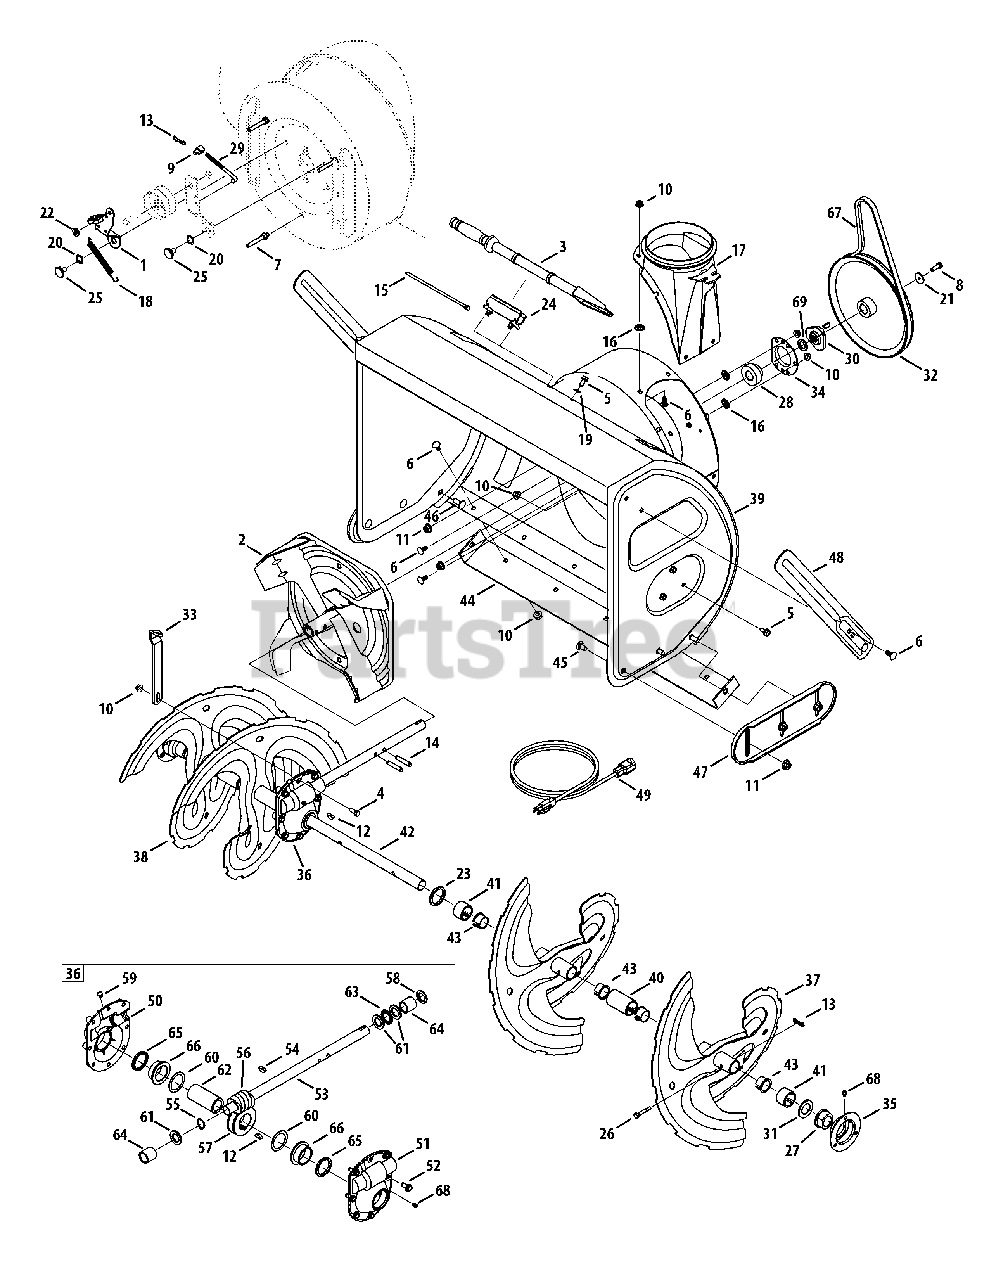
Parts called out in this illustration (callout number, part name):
1	Bracket Assy, Auger Brake
2	Impeller, 16"
3	Tool, Cleanout
4	Scr,Hex Cap, 5/16-18 x 1.00
5	Screw, 5/16-18 x .750
6	Screw, Carriage, 5/16-18 x .75
7	Screw, 5/16-18 x .4300
8	Screw, 5/16-24 x .875
9	Ferrule
10	Nut, Flnge Lk, 5/16-18
11	Nut, Flg Lk, 3/8-16
12	Key, Woodruff,1/4 x 3/4
13	Pin, Bowtie Cotter
14	Pin, Spirol, 5/16 x 1.75
15	Tie, Cable
16	Nut, Push
17	Adapter, Chute, 6"
18	Spring, Extension
19	Washer, .349 x .879 x .063
20	Washer, .625 x .885 x .015
21	Washer, Flat, .34 x 1.50 x .150
22	Washer, .344 x .75 x .12
23	Washer, 1.01 x 1.86 x .06
24	Clip, Mounting
25	Screw, Shoulder, .625 x .17
26	Pin, Shear, .25 x 1.75
27	Bearing, Flange w/Flats
28	Bearing, Self Aligning
29	Rod, Auger Idler
30	Pulley, Adapter, .75 Dia.
31	Spacer, 1.004 x 1.375 x .25
32	Pulley, Auger Drive, 10.0
33	Bracket, Gear Box Support
34	Housing, Bearing
35	Housing, Bearing
36	Gear Box Assembly, Auger
37	Spiral Assy, LH
38	Spiral Assy, RH
39	Housing, Auger - 33"
40	Spacer, 1.0 x 1.5 x 2
41	Spacer, 1.0 x 1.5 x 1
42	Axle, Spiral, 33"
43	Bushing, Flange, 1.051 x 1.16
44	Shave Plate
45	Bolt, Carriage, 3/8-16 x .750
46	Bolt, Carriage, 3/8-16 x 1.0
47	Shoe, Skid
48	Drift Cutter
49	Extension Cord, 110V
50	Hsg Assy Auger RH (Inc. 65 & 66)
51	Hsg Assy Auger LH (Inc. 65 & 66)
52	Screw, LD, 5/16-18 x .750
53	Shf, Drive, Auger
54	Key, Hi Pro, 3/16 x 3/4
55	Ext, Ret, Ring
56	Gear, Worm, Dbl Thread
57	Gear, Worm, LH
58	Seal, Oil
60	Washer, Flat, 1.52 ID x 2.0 OD
61	Washer, Flat, .88 ID x .38 OD
62	Shf, Gear, Worm
63	Brg, Thrust
64	Sleeve
65	Oil Seal
66	Flange Bearing
67	V Belt,4L x 44.60 Lg.
68	Lube Fitting, 3/16 #70
69	Washer, Flat, .78 x 1.49 x .08
